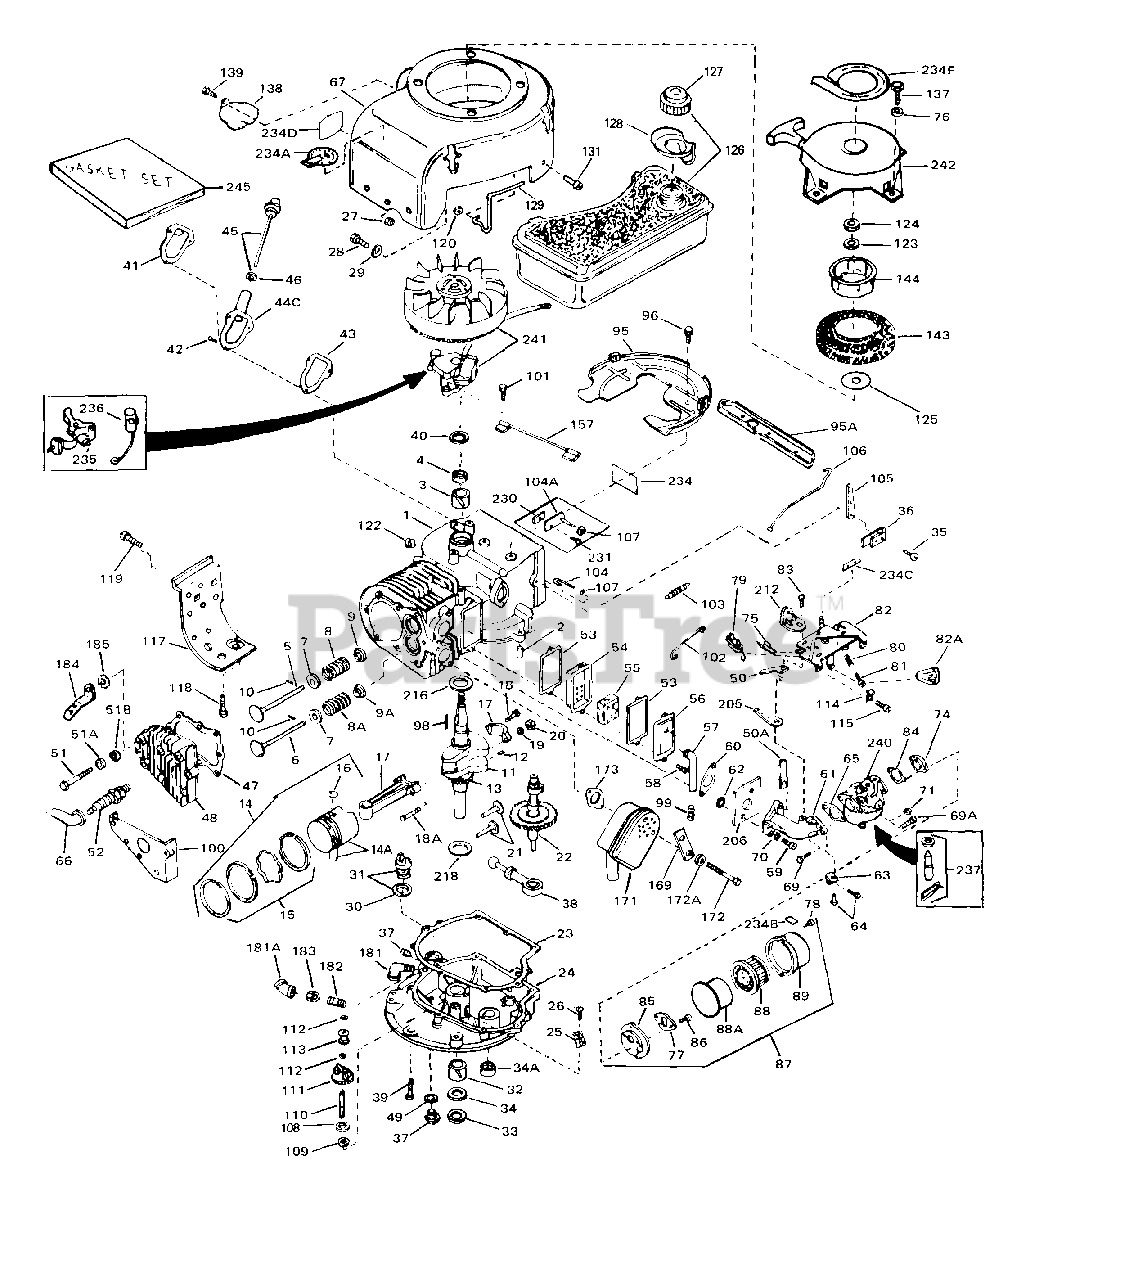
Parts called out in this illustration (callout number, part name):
1	"Cylinder Assy. (2-5/8" Bore)
2	Pin, Dowel
3	Bushing, Crankshaft
4	Seal, Oil
5	Valve, Intake (Standard)
5	Valve, Intake (1/32" oversize)
6	Valve, Exhaust (Standard)
6	Valve, Exhaust (1/32" oversize)
7	Cap, Upper valve spring
8	Spring, Valve
8A	Spring, Valve
9	Cap, Lower valve spring (Standard)
9	Cap, Lower valve spring (1/32" oversi ze)
9A	Cap, Lower valve spring (Standard)
9A	Cap, Lower valve spring (1/32" oversi ze)
10	Pin, Valve spring retaining
11	Crankshaft Assy.
12	Pin, Crankshaft gear
13	Gear, Crankshaft
14	Piston, Pin & Ring Assy. (Std.) (2-5/ 8")
14	Piston, Pin & Ring Assy. (.010 oversi ze)
14	Piston, Pin & Ring Assy. (.020 oversi ze)
14A	Piston & Pin Assy. (Std.) (2-5/8")
14A	Piston & Pin Assy. (.010 oversize)
14A	Piston & Pin Assy. (.020 oversize)
15	Ring Set, Piston (Std.) (2-5/8")
15	Ring Set, Piston (.010 oversize)
15	Ring Set, Piston (.020 oversize)
16	Ring, Piston pin retaining
17	Rod Assy., Connecting
18	Bolt, Connecting rod
18A	Bolt, Connecting rod
19	Washer, Connecting rod bolt
21	Lifter, Valve
22	Camshaft (Mech. Compression Release)
23	Gasket, Mounting flange
24	Flange, Mounting
25	Screen, Oil filter
30	Gasket, Filler plug
31	Plug, Oil filler
32	Bushing, Crankshaft
34	Seal, Oil
34A	Seal, Oil (Camshaft)
35	Screw, Hex washer hd., 8-32 x 5/16
36	Clamp, Governor lever
37	Plug, Drain
38	Pump Assy., Oil
39	Screw
41	Cover, Oil filler hole
42	Screw, Phil. Rd. hd., w/neoprene wash er,
43	Gasket, Oil filler tube
47	Gasket, Cylinder head
48	Head, Cylinder
49	Gasket, Oil drain
50	Clip, Fuel line
50A	Clip, Fuel line
51	Screw, Hex flange hd., 5/16-18 x 2
51	Screw, Hex flange hd., 5/16-18 x 2-1/ 2
51A	Washer, Flat
51A	Washer, Belleville
51B	Washer, Flat
52	Plug, Spark (Champion J-8 or equivale nt)
52	Resistor Spark Plug
53	Gasket, Breather cover
54	Body, Breather
55	Element, Breather
56	Cover, Valve chamber
57	Tube, Breather
60	Gasket, Intake pipe
61	Pipe, Intake
65	Gasket, Carburetor
66	Cover, Spark plug
69	Screw
70	Lockwasher
74	Flange, Air cleaner
76	Washer, Flat
77	Spacer, Air cleaner
79	Terminal Assy.
80	Spring, Compression
81	Screw
82	Control Assy., Speed
84	Gasket, Air cleaner
85	Bracket, Air cleaner
86	Screw
87	Cleaner Assy., Air (Poly)
88	Element, Air cleaner
89	Body, Air cleaner
95	Baffle, Blower housing
98	Key, Flywheel
99	Spring, Coil
100	Cover, Cylinder head
102	Link, Governor spring
103	Spring, Governor
104	Rod, Governor
105	Lever, Governor
106	Link, Throttle
107	Washer, Flat
109	Spacer Assy., Governor
110	Shaft, Mechanical governor
111	Gear Assy., Governor
112	Ring, Retaining
113	Spool, Governor
114	Clip, Conduit
117	Extension, Blower housing
119	Screw, Hex hd. Sems, 1/4-20 x 1/2
122	Clip, Hi-tension wire
123	Washer, Belleville
127	Cap, Fuel filler (Red Plastic) (Spurt
127	Cap, Fuel filler (White Plastic) (Std .)
131	Screw
137	Screw, Fil. hd., 1/4-28 x 2
143	Screen, Starter cup
144	Cup, Starter
157	Wire, Ground (Female fitting both end s)
164	Screen, Muffler
169	Plate, Muffler locking
171	Muffler
172	Screw, Hex flange hd., 5/16-18 x 1-1/ 2
172	Screw, Hex flange hd., 5/16-18 x 2-1/ 4
172	Screw, Hex hd., 5/16-18 x 2-3/4
172	Screw, Hex flange hd., 5/16-18 x 2-1/ 2
172A	Lockwasher
173	Gasket, Exhaust
181	Elbow, Oil drain (90(deg))
184	Clip, Shorting
185	Lockwasher
206	Baffle, Air
234	Decal, Instruction
234A	Decal, H.P. (4 H.P.)
234A	Decal, H.P. (5 H.P.)
234A	Decal, H.P. (6 H.P.)
234A	Decal, Name
234B	Decal, Air cleaner
234C	Decal, Speed control
234D	Decal, Oil
235	Contact Assy., Breaker
236	Condenser
237	Inlet Needle, Seat & Clip Assy.
240	Carburetor
241	Magneto, Tecumseh
242	Starter, Rewind
245	Gasket Set
